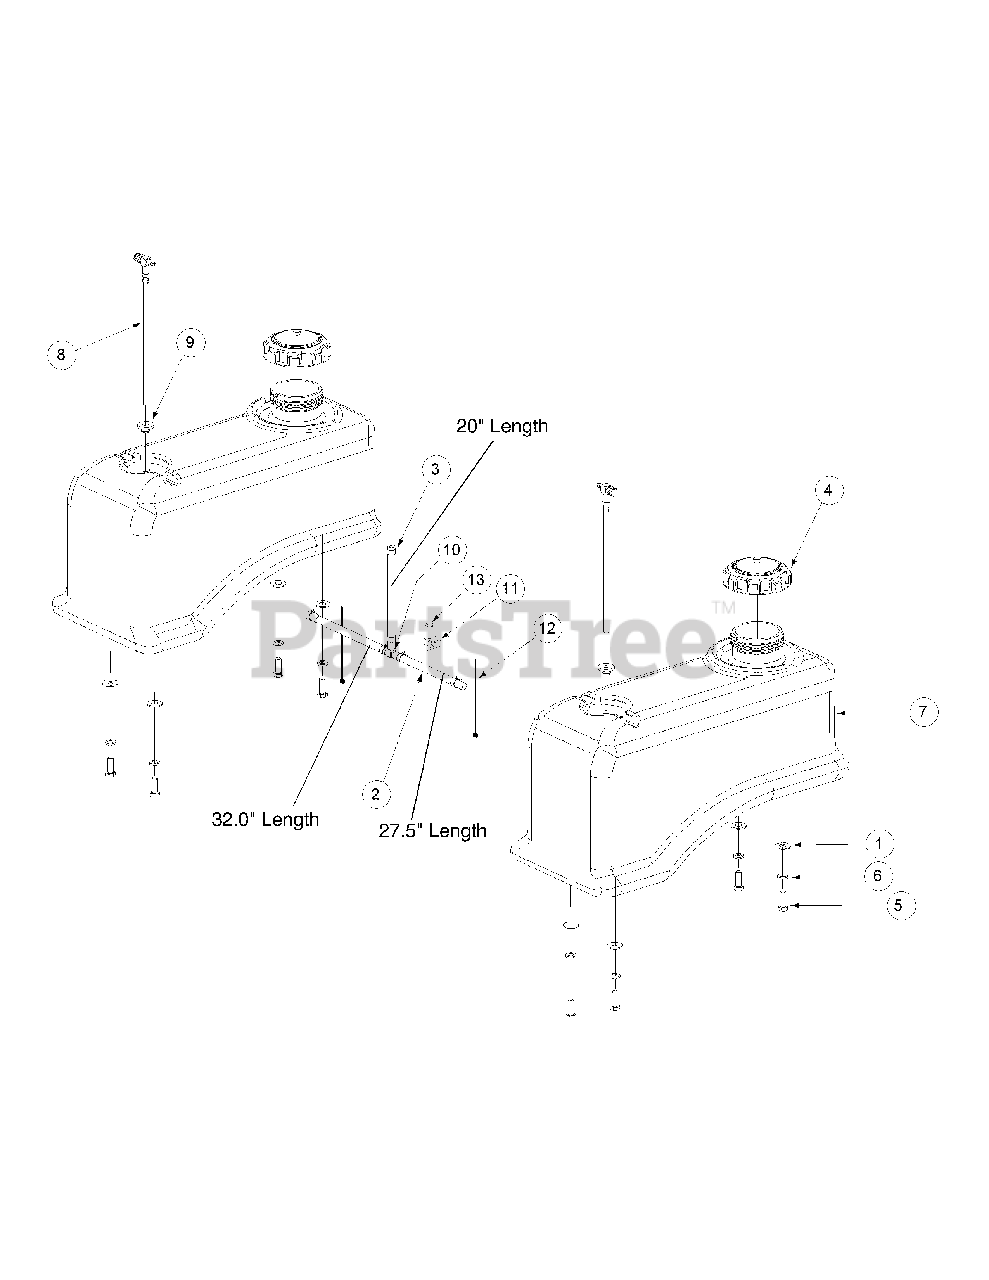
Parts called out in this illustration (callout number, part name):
1	Flat Washer, .406 ID, 1.0 OD, .105
2	Hose, 1/4" Fuel Line 88 in inches
3	Clamp, Union
4	Fuel Cap, 3.5
5	Hex, Cap Screw, 3/8-16, .88
6	Lock Washer, 3/8
7	Fuel Tank
8	Fuel Fitting
9	Fuel Tank Grommet
10	Tee Fitting, Fuel
12	Cable Tie
13	Flatwasher 1/4 x .630 x .0515
